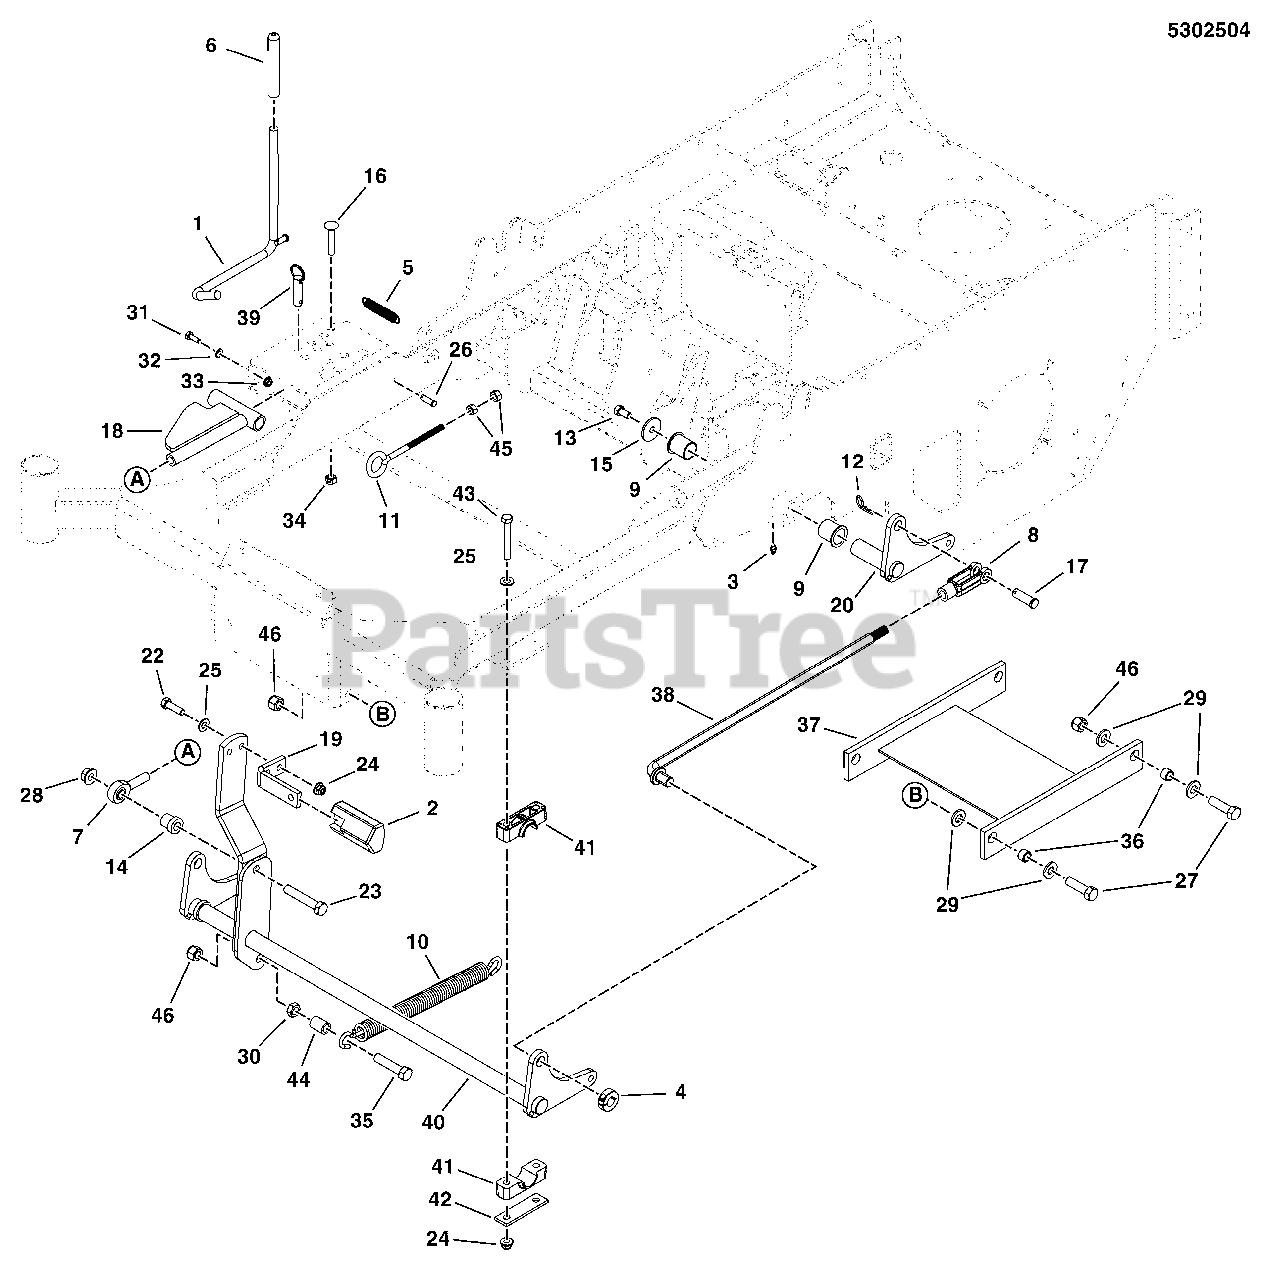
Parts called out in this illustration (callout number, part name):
1	WELD, ROD DECK LIFT - BLK
2	PEDAL, Rubber
3	GREASE FITTING, 1/4-28 STRAIGHT
4	COLLAR, 5/8 SPLIT
5	SPRING-EXT, .500 OD X 3.50 LG X .058 WR
6	GRIP, FOAM
7	BALL JOINT, 1/2-20, MALE
8	CLEVIS, 1/2-20, STEEL
9	BUSHING, 1.00 X 1.13 X 1.38, PLASTIC
10	SPRING-EXT, 1.00 ODX13.25LGX.177WR, BLK
11	EYE BOLT, 3/8-16 X 8, 1 EYE
12	PIN, HAIR, .0915 X 1-7/8
13	BOLT, 3/8-16 X 3/4, GD5, YZ WITH PATCH
14	SPACER, .53 X 1.00 X 1.00, CZ
15	WASHER, .390 X 1.50 X .109, YZ
16	BOLT, 3/8-16 X 2, CARRIAGE
17	PIN, CLEVIS, 1/2 X 1 1/2, YZP
18	WELD, DECK ADJUST LINK - RED
19	PEDAL, FOOT - BLK
20	PIVOT, DECK LIFT WELD - LEFT - BLK
22	BOLT, 3/8-16 X 1-1/4" GD5 CZ
23	BOLT, 1/2-13 X 2-3/4 GD5 CZ
24	NUT, 3/8-16 HEX NYLOCK FLANGE
25	WASHER, 3/8 SAE
26	PIN, CLEVIS, 1/4 X 7/8, PLATED
27	BOLT, 1/2-20 X 1-3/4" GD8 CZ
28	NUT, Hex Flange, Nylock, 1/2-13
29	WASHER, 1/2 GD9 YZ
30	NUT, 1/2-20 HEX JAM
31	BOLT, 1/4-20 X 3/4 GD5 YZ
32	WASHER, 1/4 SAE
33	NUT, 1/4-20 HEX SERR. FLANGE
34	NUT, 3/8-16 HEX SIDE LOCK
35	BOLT, 1/2-20 X 2-1/4 GD5 CZ
36	INSERT, BEARING
37	WELD, Deck Stabilizer - Blk
38	ROD, DECK LIFT, SNP
39	PIN, HITCH, 1/2 X 2.00 OAL, YP
40	WELD, DECK LIFT SHAFT-SNP PRO- RED
41	PIVOT BLOCK, PLASTIC
42	PLATE, PIVOT BLOCK SUPPORT - BLK
43	BOLT, 3/8-16 X 2-3/4" GD5 CZ
44	HOSE, 1/2 PUSH-LOCK, 3.00"
45	NUT, 3/8-16 HEX
46	NUT, Hex, Nylon Lock, 1/2-20
